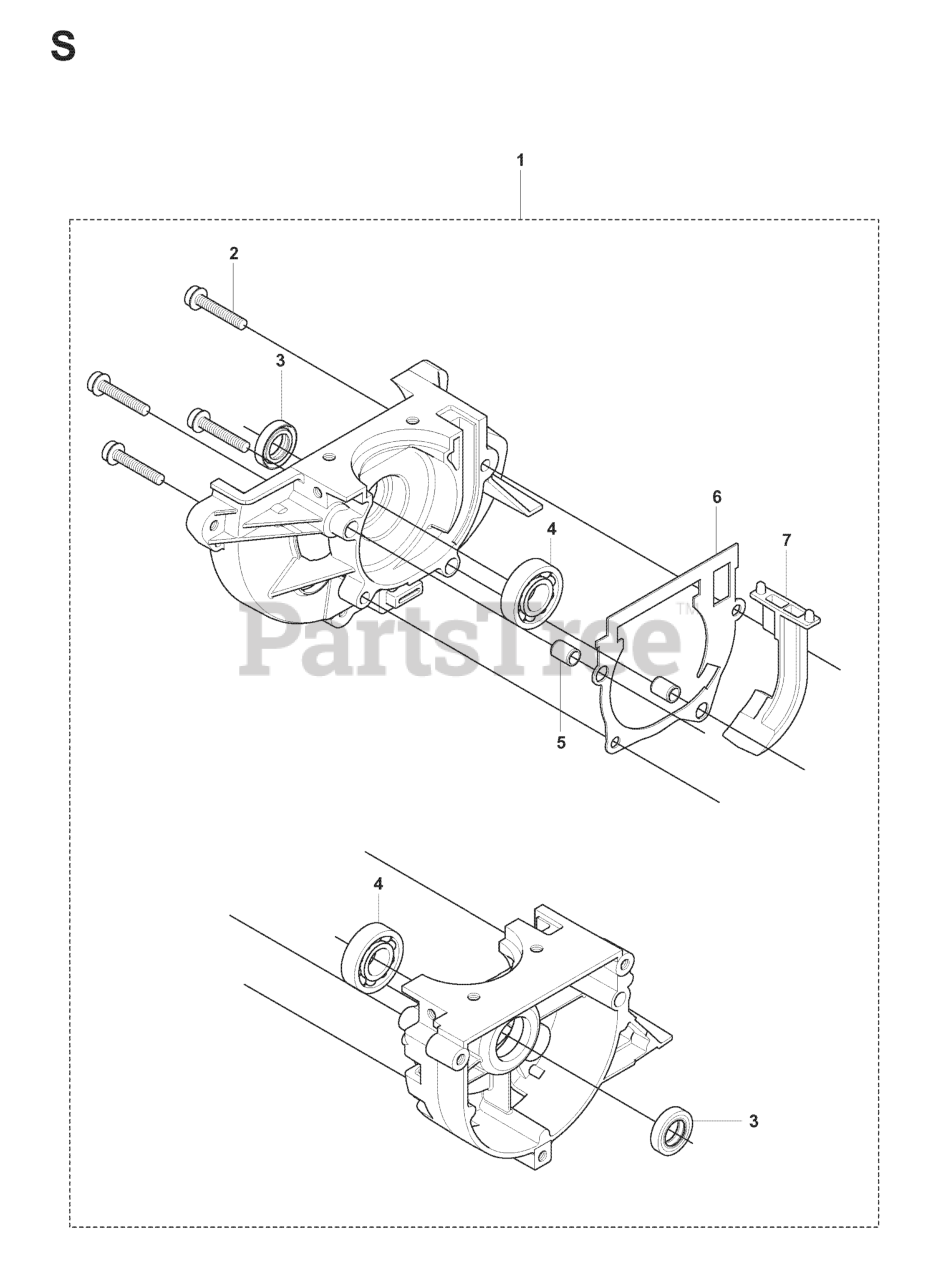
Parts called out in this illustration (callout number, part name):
1	CRANKCASE ASSY SPARE
3	SEALING RING
4	BALL BEARING
